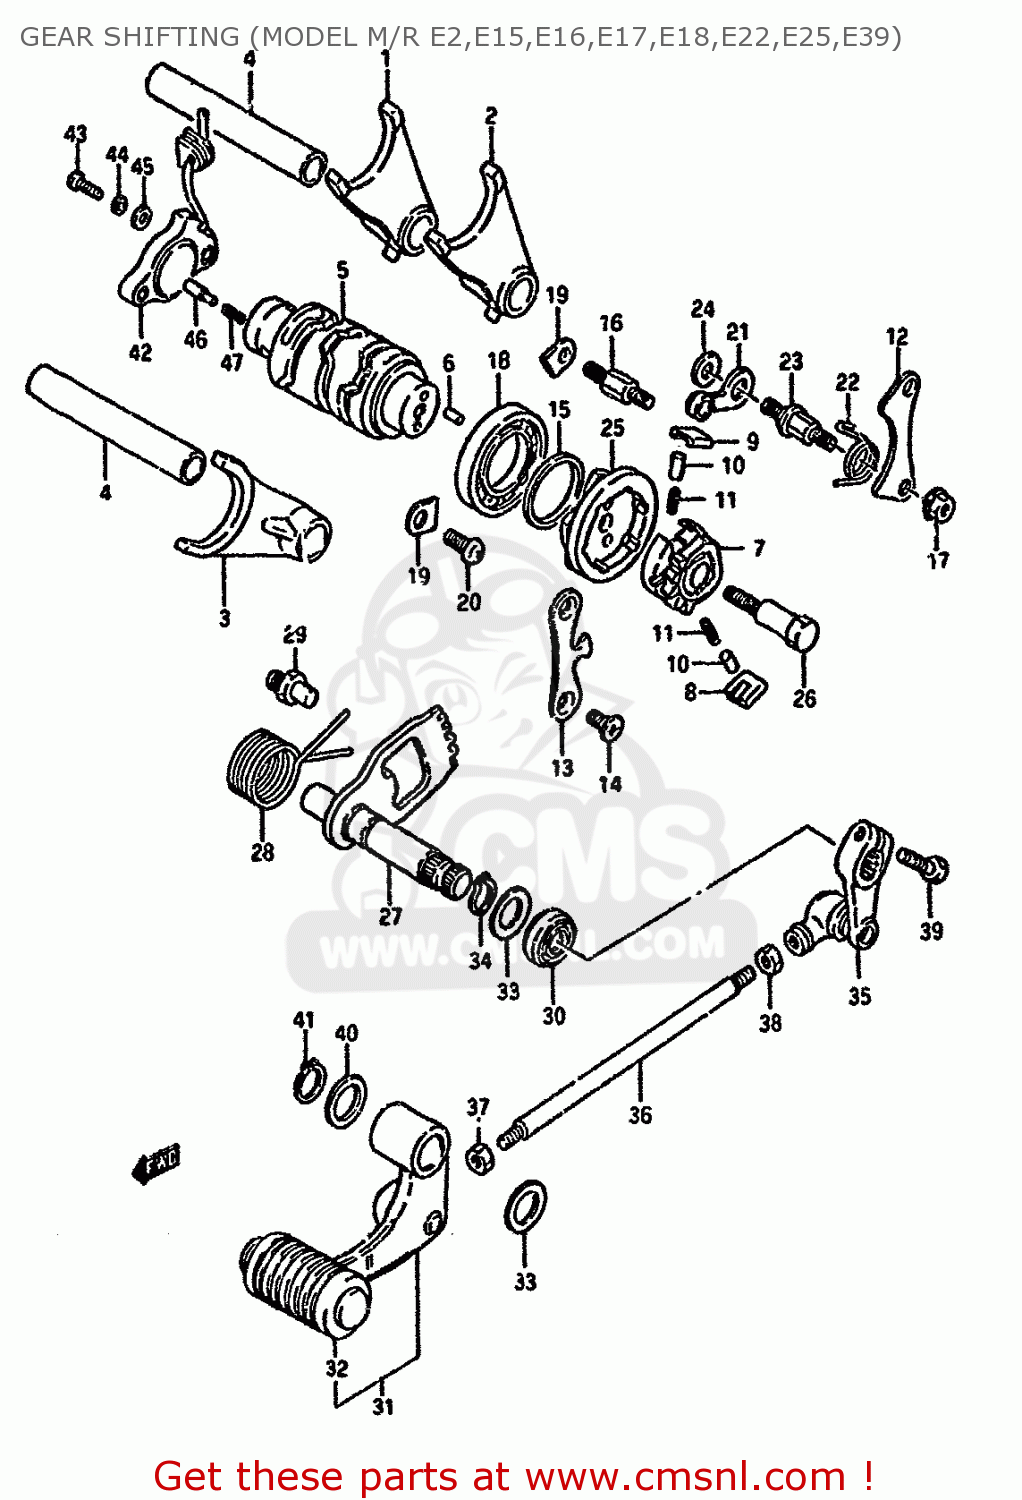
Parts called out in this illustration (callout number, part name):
1	FORK,GEAR SHIFT NO.1
2	FORK,GEAR SHIFT NO.2
3	FORK,GEAR SHIFT NO.3
4	SHAFT,GEAR SHIFT FORK
5	CAM,GEAR SHIFT
6	PIN
7	GEAR,GEARSHIFT CAM DRIVE
8	PAWL,GEAR SHIFT NO.1
9	PAWL,GEAR SHIFT NO.2
10	PIN(5X8)
11	SPRING
12	LIFTER,GEAR SHIFT POLE
13	GUIDE,GEAR SHIFT CAM
14	SCREW
15	WASHER(25X32X3)
16	BOSS,SHIFT PAWL LIFTER
17	NUT
18	BEARING
19	RETAINER
20	SCREW 6X12
21	STOPPER,GEAR SHIFT CAM
22	SPRING
23	SPRING,STOPPER ARM
24	WASHER
25	PLATE,GEAR SHIFT CAM
26	PIN,SHIFT CAM DRIVEN GEAR
27	SHAFT,GEAR SHIFT
28	SPRING
29	STOPPER,GEAR SHIFT CAM
30	OIL SEAL
31	LEVER ASSY,GEAR SHIFT
32	RUBBER,GEAR SHIFT PEDAL
33	WASHER(12.5X20X1)
34	CIRCLIP,12 MM
35	ARM,GEAR SHIFT LINK
36	ROD,GEAR SHIFT LINK
37	NUT
38	NUT 6MM
39	BOLT
40	WASHER
41	CIRCLIP,12 MM
42	BASE ASSEMBLY,NEUTRAL SWITCH TERMINAL
43	SCREW
44	LOCK WASHER
45	WASHER
46	PIN(5X15.5)
47	SPRING
